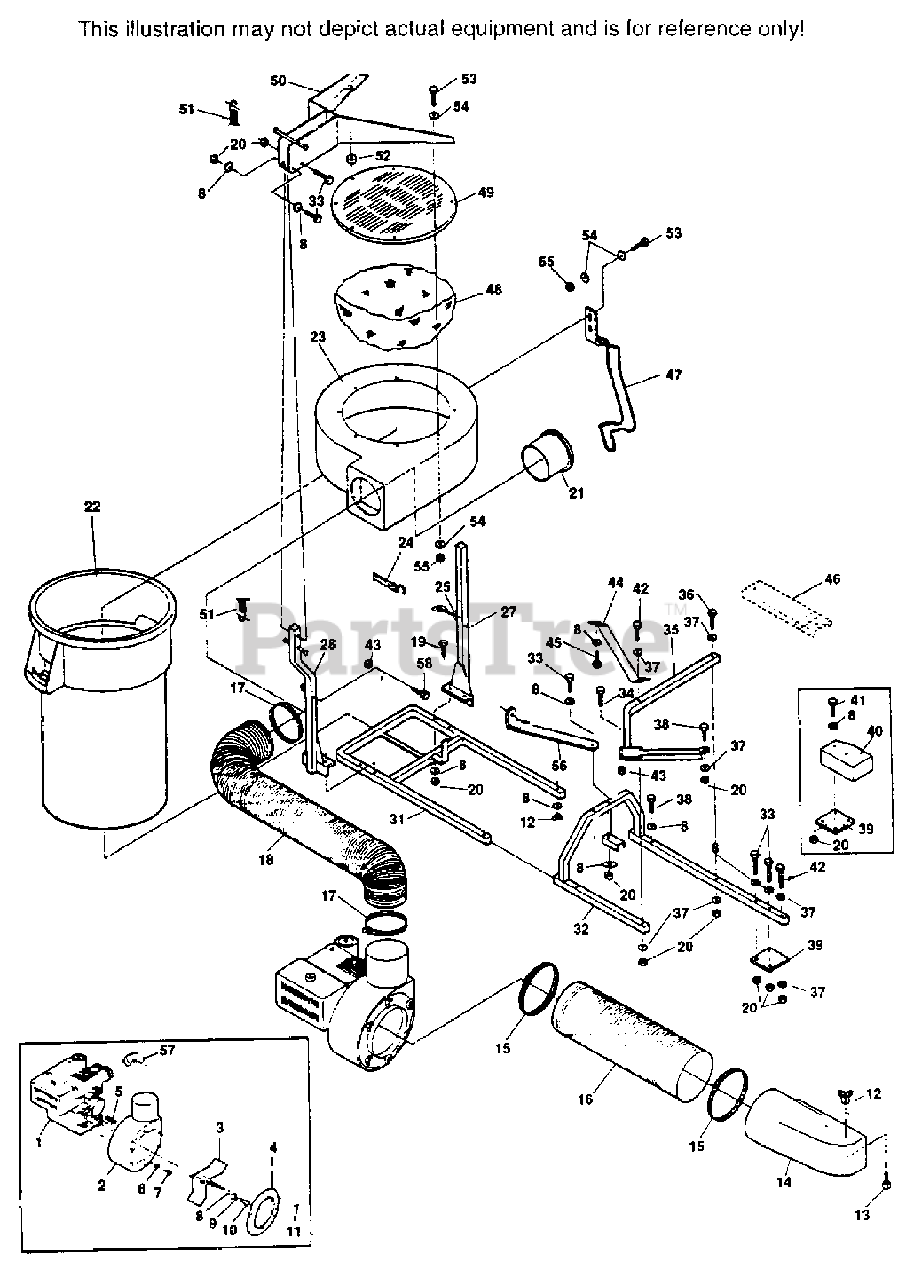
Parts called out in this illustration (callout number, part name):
1	ENGINE, 5 HP I.C.(1" CRANKSHAFT)
2	BLOWER HOUSING ASSEMBLY
3	FAN ASSEMBLY(1" BORE)
4	INLET ADAPTOR
5	KEY 1/4 X 1/4 X 1-1/2"(FOR 1" CRANKSHAFT
7	BOLT, 5/16-24 X 1"
8	WASHER, 3/8(15/16 X 25/64 X 12GA.)
11	WING NUT, 5/16-18
12	WING NUT, 3/8-16
14	BOOT
15	CLAMP 8"
16	HOSE 8"
17	CLAMP 6"
18	HOSE 6"
20	NUT, 3/8-16 ELASTIC STOP
21	INTAKE NOZZLE
22	BUCKET
23	MOULDED TOP
24	RUBBER STRAP
25	EYEBOLT, 5/16-18 X 2-3/4"
27	BUCKET BRACE-LH
28	BUCKET BRACE-RH
31	BUCKET SUPPORT FRAME
32	MAIN FRAME
35	ENGINE MOUNTING FRAME
37	WASHER, 3/8 X 1-1/2 X 7 GA.
39	BALLAST SUPPORT
40	BALLAST
43	NUT, 5/16-18 ELASTIC STOP
44	ENGINE FRAME BRACE
46	FRAME EXTENSION
47	CONTAINER LATCH
48	MESH FILTER
49	FILTER SUPPORT
50	COVER BRACKET
51	SPRING
52	SPACER
56	UPRIGHT POST BRACE
57	EXHAUST DEFLECTOR W/SCREW
